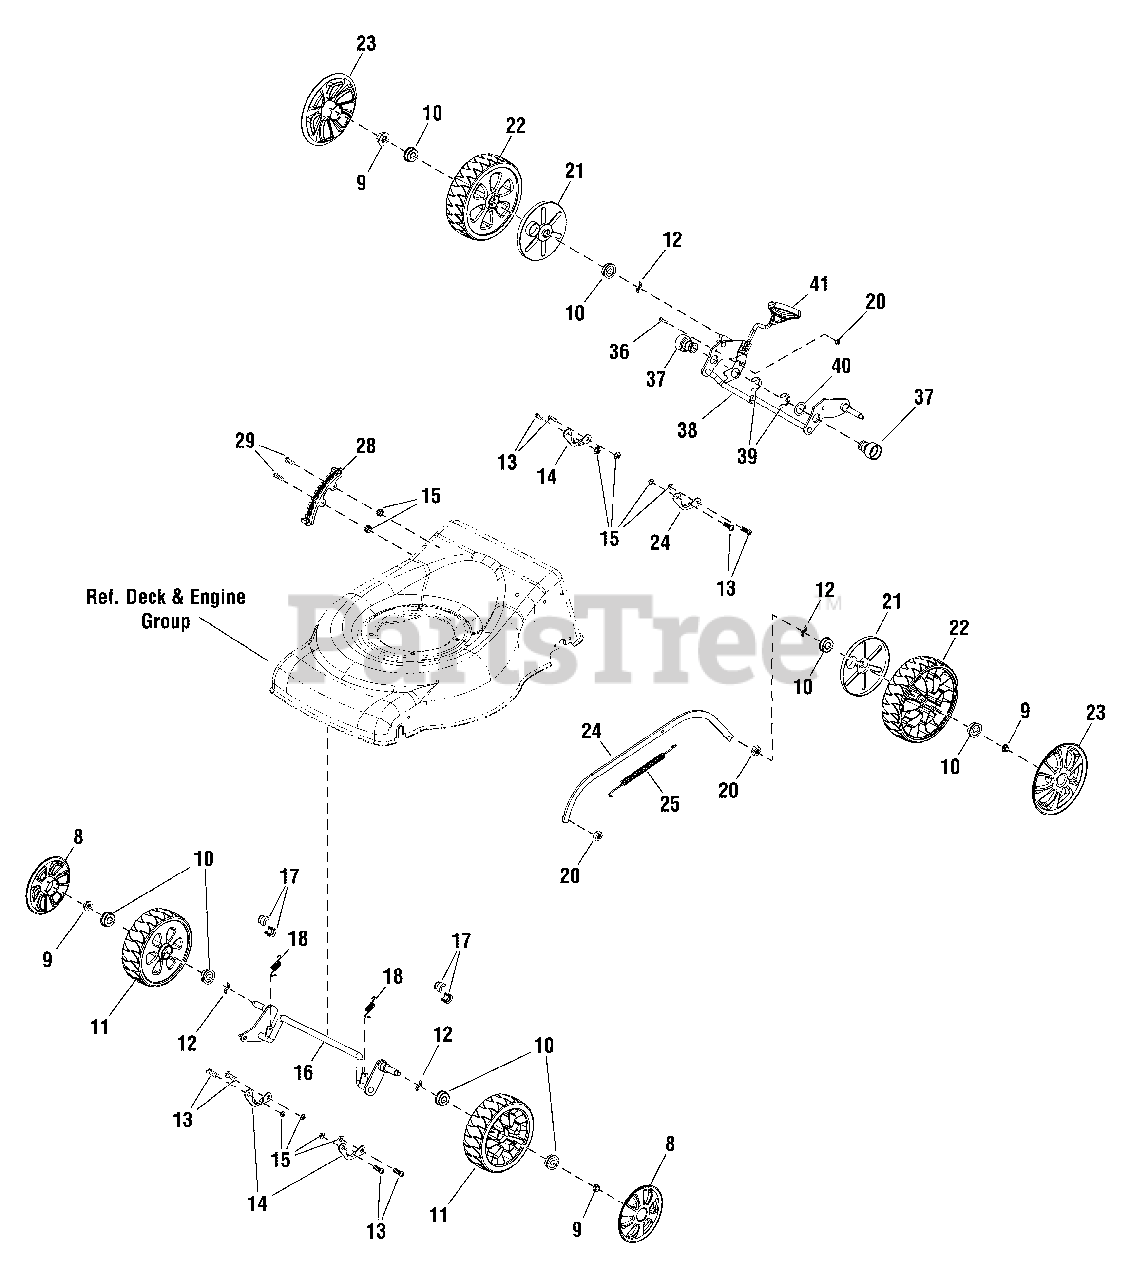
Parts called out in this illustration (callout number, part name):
8	HUBCAP, Front
9	* NUT, Hex Lock
10	BEARING
11	WHEEL ASSEMBLY, Front
12	WASHER, Wave
13	* SCREW
14	BRACKET, Wheel Axle
15	* NUT, Hex Lock
16	AXLE ASSEMBLY, Front
17	BEARING HOLDER
20	* NUT, Hex Lock
21	DUST COVER
22	WHEEL ASSEMBLY, Rear
23	HUBCAP, Rear
24	CONNECTING LINK
28	BRACKET, Height of Cut
29	* SCREW
36	SCREW, Pan Head
37	HOLDER, Bearing
38	AXLE ASSEMBLY, Rear
39	WASHER, Split
40	WASHER, Adjusting
41	HEIGHT ADJUSTMENT ASSEMBLY
